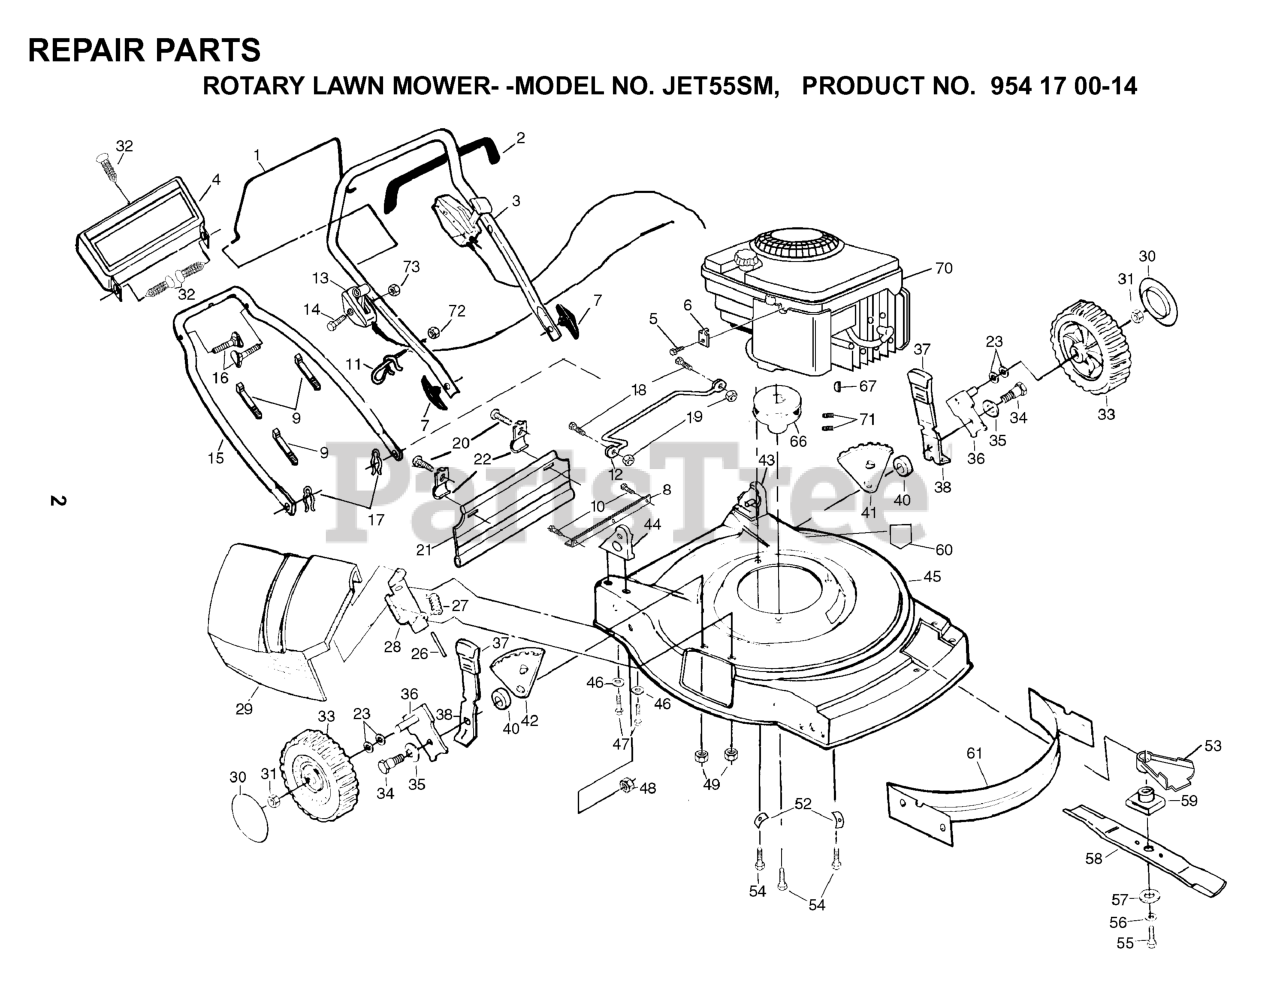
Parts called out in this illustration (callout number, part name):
1	CONTROL BAR
2	GRIP.HANDLE.FOAM
4	TRIM PLATE
5	SCREW.HEX.HEAD.WASHER.10-16
6	WASHER
7	HANDLE KNOB
9	TIE GUIDE
11	ROPE GUIDE
13	THROTTLE CONTROL
14	SCREW 1/4-20X1.75
15	HANDLE, LOWER
16	HANDLE BOLT
17	HAIRPIN COTTER
18	REPL BY 817 02 10-08
20	TAPPING SCREW
21	REAR SKIRT
22	BRACKET DEFL PM
23	WAVE WASHER
26	ROD.HINGE.COMBI-C
28	BRACKET PM
29	DISCHARGE GUARD
30	HUBCAP.8".GREY
31	HEX FLANGE LOCKNT
33	WHEEL.8X2.PR.LP.RAD.GREY
34	BOLT
35	WASHER.BELLEVILLE (3 2 LB)
36	AXLE ARM
37	SELECTOR KNOB
40	RP SPACER HT ADJ
41	WHL ADJ BRKT RF/LR
42	WHL ADJ BRKT LF/RR
43	HDLE BRKT ASSY LH
44	HDLE BRKT ASSY RH
47	SCREW.5/16-18X3/4
48	LOCKNUT PM
49	NUT
52	WASHER.ENGINE.BZP
53	DEBRIS SHIELD
54	BOLT 3/8-16X1-1/8
55	SCREW, HEX HD 3/8-24 X 1-3/8
56	LOCKWASHER
57	WASHER,HARDEN
59	BLADE ADAPTOR
60	DECAL MOWER CUT/FINGER
66	ENGINE.PULLEY.FWG
67	HI PRO KEY PM WSL
72	NUT
73	NUT
74	RIVET BLIND
